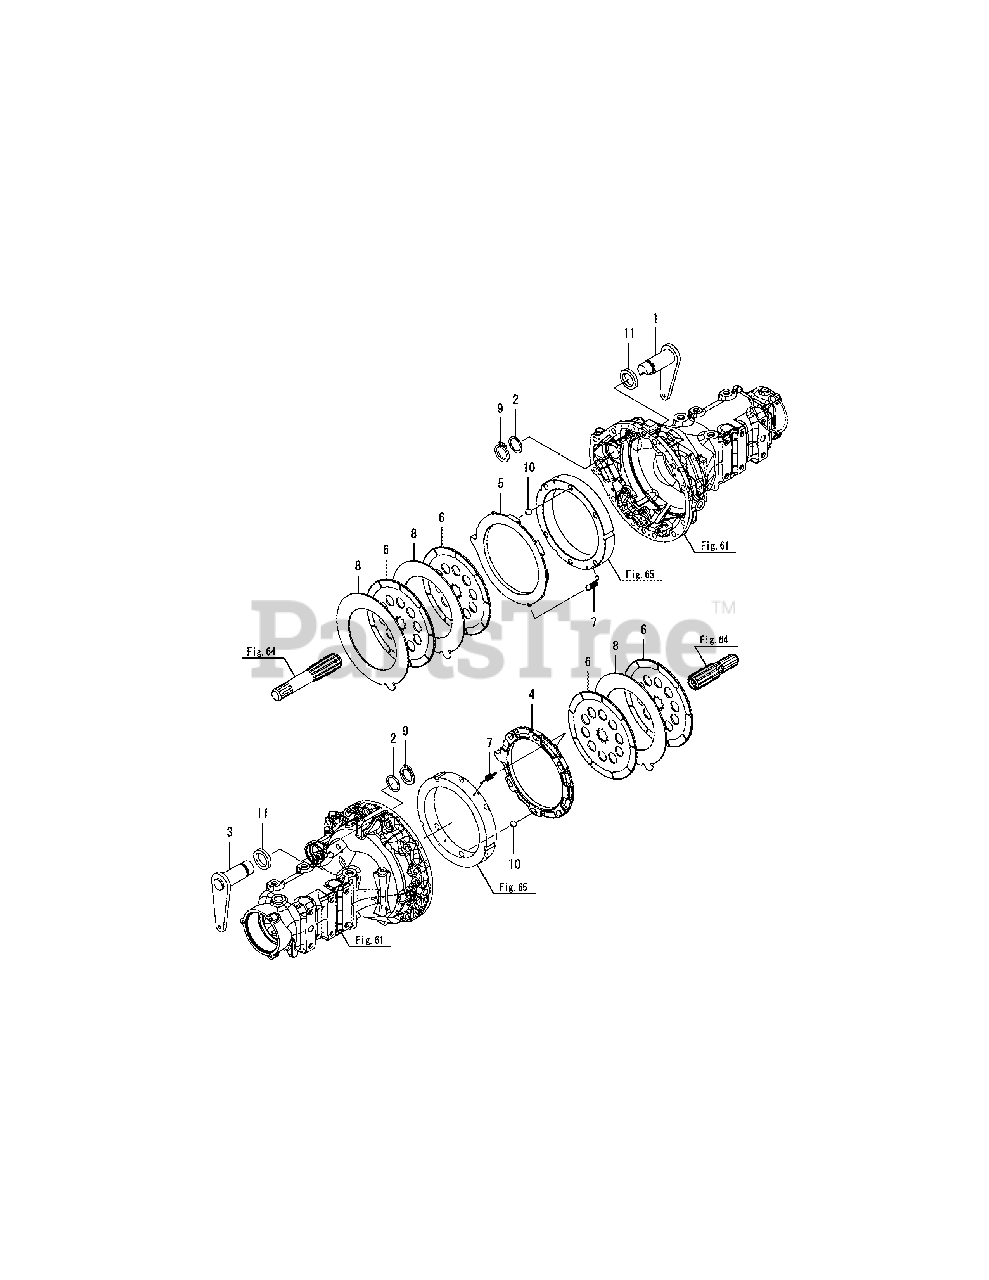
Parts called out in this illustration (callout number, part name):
1	CAM-LEVER, R ASSY
2	WASHER, THRUST
3	CAM-LEVER, L ASSY
4	ACTUATOR, L.H.
5	ACTUATOR, R.H.
7	SPRING, RETURN
8	PLATE, STEEL 3.2
11	SEAL TC35 50 08, OIL
